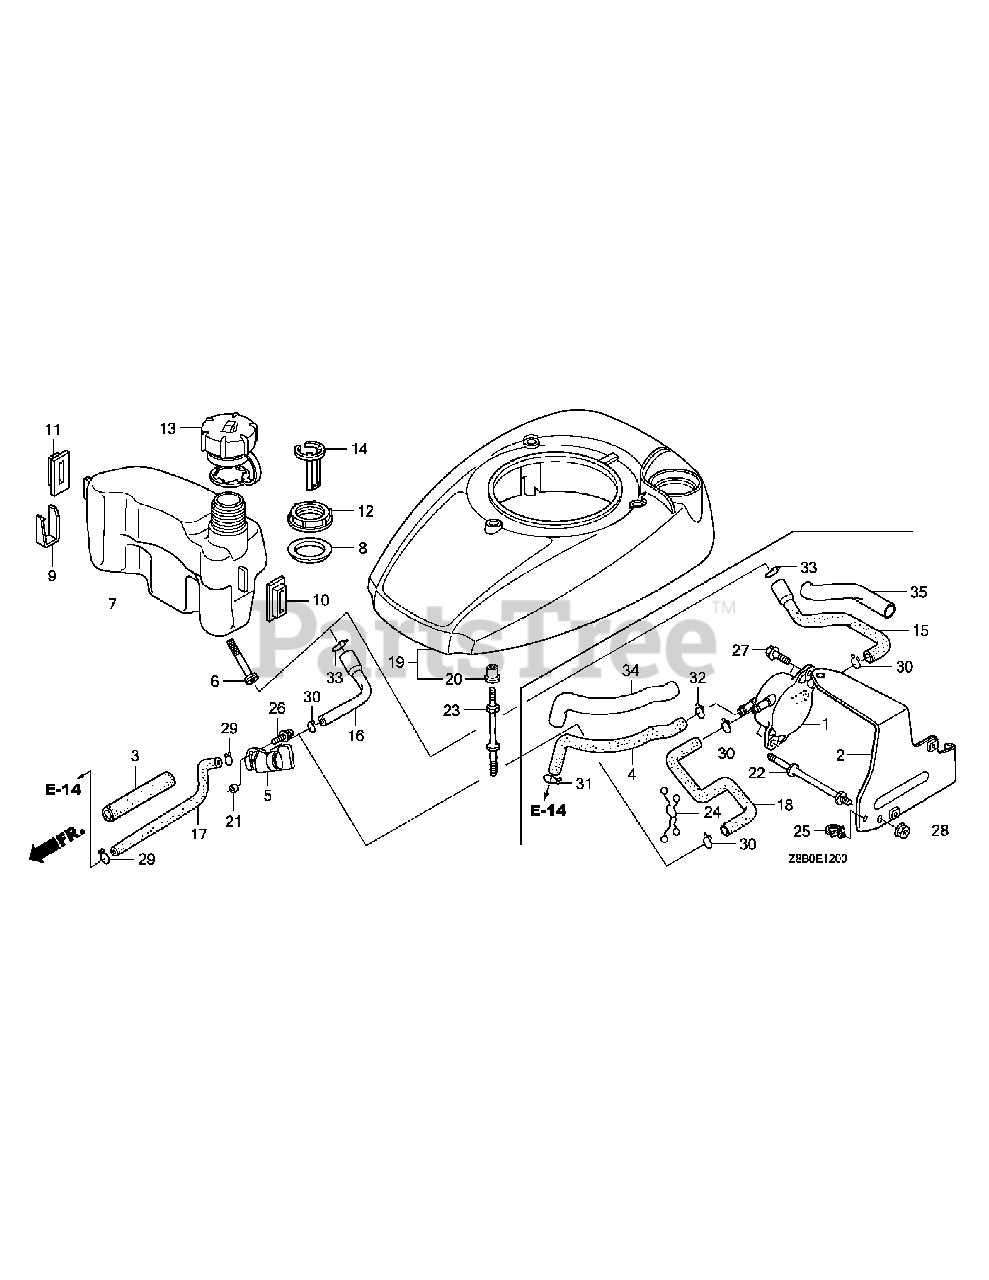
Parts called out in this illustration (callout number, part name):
1	PUMP ASSY., FUEL
2	STAY, FUEL PUMP
3	RUBBER, SUPPORTER (107MM)
4	TUBE, DIAPHRAGM
5	COCK ASSY., FUEL
6	STRAINER, FUEL
7	TANK, FUEL
8	SEAL, FUEL FILLER NECK
9	CLIP, TANK MOUNTING
10	RUBBER A, TANK MOUNTING
11	RUBBER B, TANK MOUNTING
12	NUT, TANK MOUNTING
13	CAP ASSY., FUEL TANK
14	GAUGE, FUEL LEVEL
15	TUBE, FUEL TANK
16	TUBE, FUEL TANK
17	TUBE, FUEL
19	COVER COMP., FAN
20	COLLAR, FAN COVER
21	COLLAR, FUEL COCK
22	BOLT, STUD
23	BOLT, STUD
24	CLIP, PURSE LOCK
25	CLIP, WIRE HARNESS
26	SCREW-WASHER, 5X10
27	SCREW-WASHER, 5X14
28	NUT, FLANGE, 6MM
29	CLIP, TUBE (B8)
30	CLIP, TUBE (B10)
31	CLIP, TUBE (C8)
32	CLIP, TUBE (C9)
33	CLIP, TUBE (C11)
34	TUBE, VINYL, 9X11X210
35	TUBE, VINYL, 13X15X90
